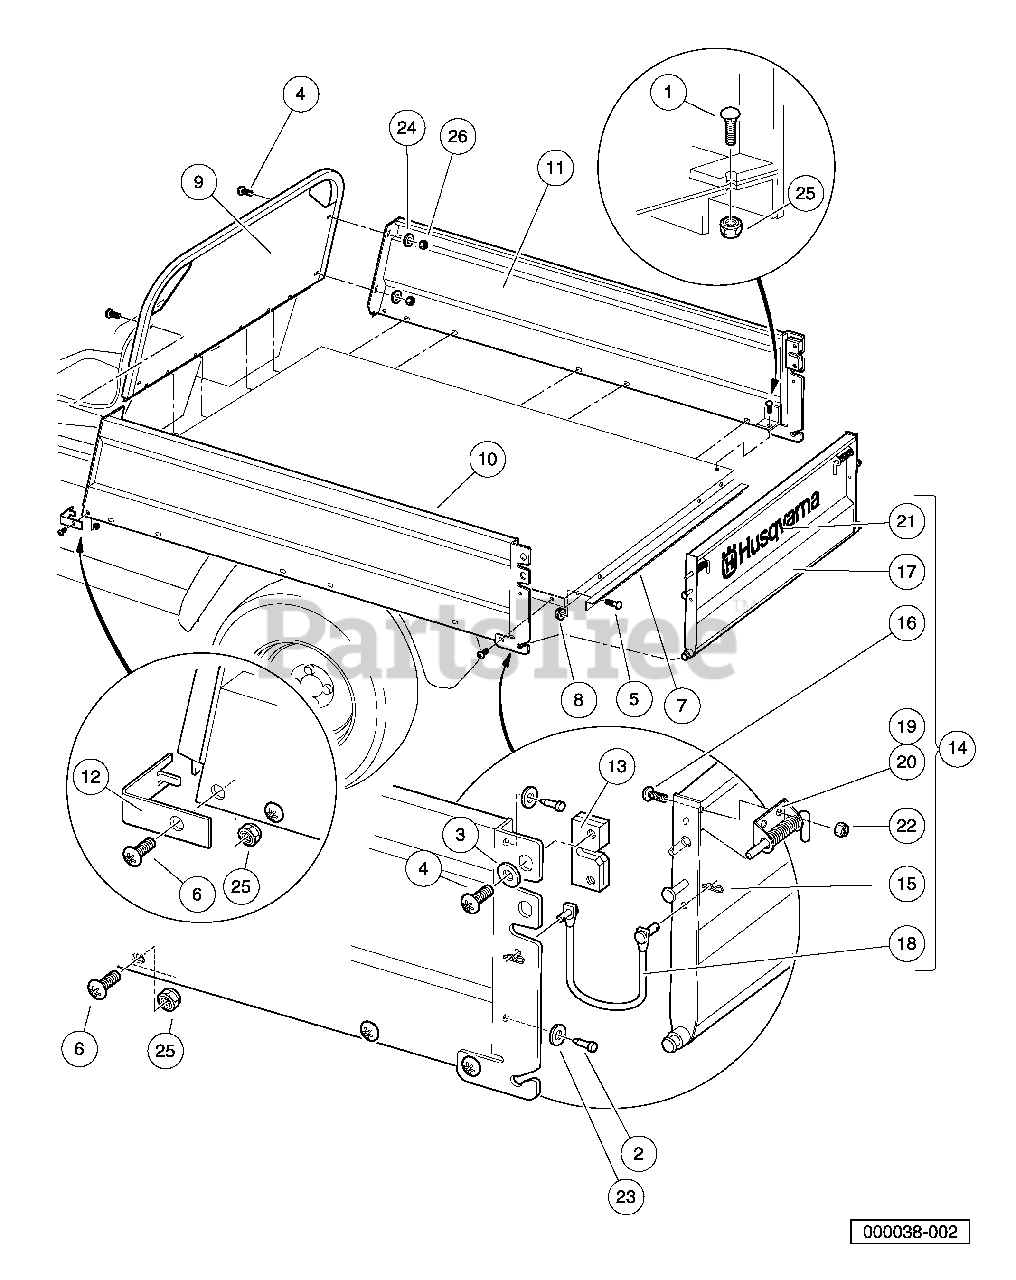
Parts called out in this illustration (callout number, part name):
1	Bolt, Carriage, 5/16-18 X 1.00
2	Bumper, Rubber
3	Washer, 1/4" Type B Flat
4	Screw, 1/4-20 X 0.75 Torx Truss-Head
5	Stud, Self-Clinching Flush Head
6	Screw, 5/16-18 X 0.88 Torx Truss-Head
7	Box Bed Tailgate Angle
8	Locknut, 5/16-18 Hex Flange
9	Front Panel Weldment
10	Left Panel Weldment
11	Right Panel Weldment
12	Front Corner Cap
13	Slam Latch
14	Assembly, Tailgate
15	Hair Pin Clip
16	Screw, 1/4-20 X 0.75 Torx Truss-Head
17	Tailgate, Weldment
18	Tether Assembly
19	Spring Latch Left
20	Spring Latch Right
21	Decal, Husqvarna, Tailgate
22	Locknut, 1/4-20 Nylon Insert
23	Washer, Rubber, 3/8
24	Washer, 1/4 Type A Narrow Flat
25	Locknut, 5/16-18 Nylon Insert
26	Locknut, 1/4-20 Nylon Insert
